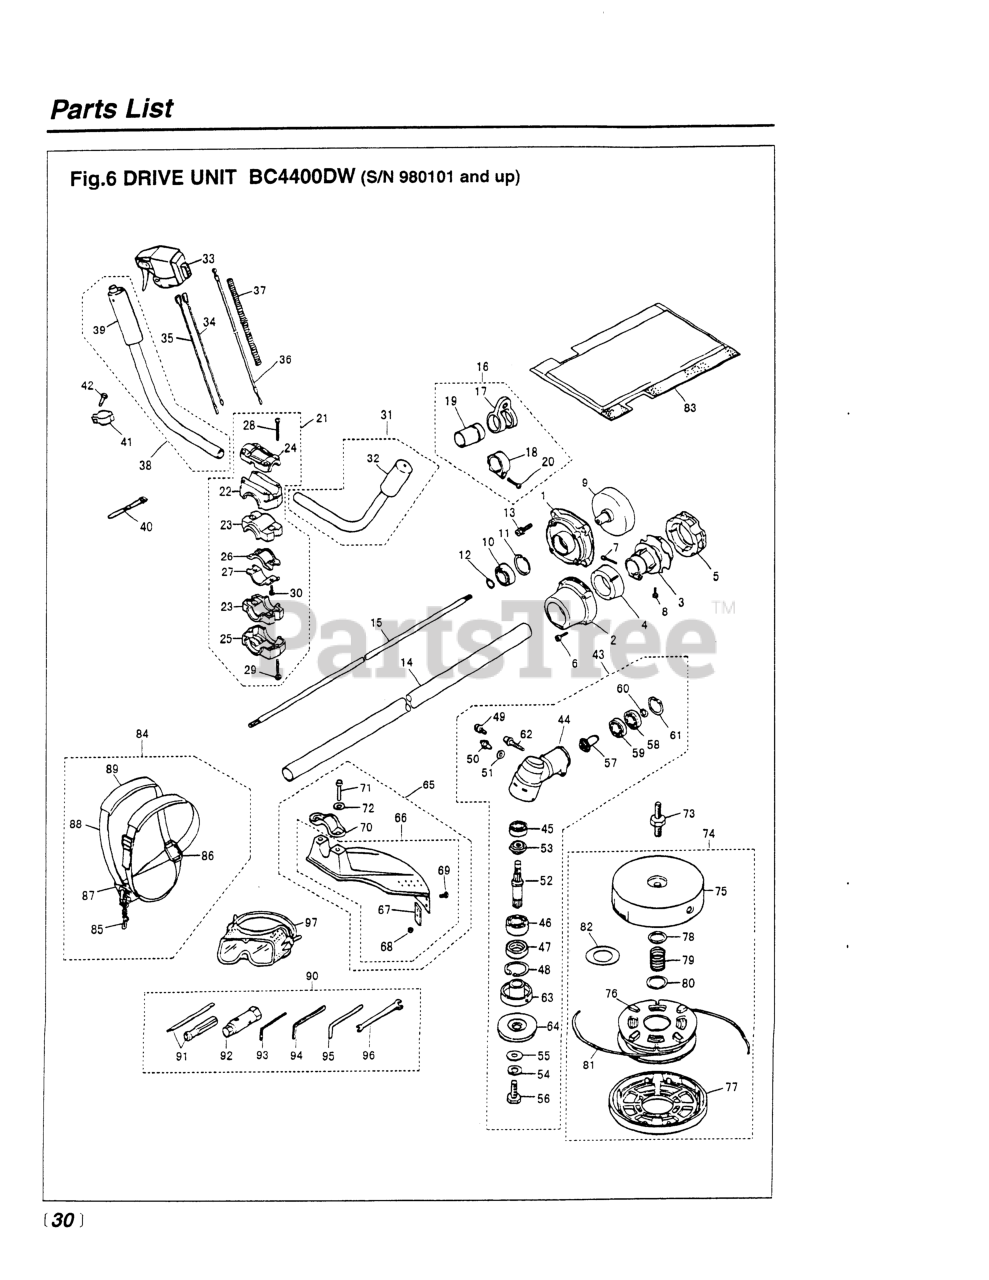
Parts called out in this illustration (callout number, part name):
1	HOUSING
2	CAP
3	JOINT
4	ABSORBER-F
5	ABSORBER-R
6	BOLT, M5 X 30
7	BOLT, M6 x 30
8	BOLT, M5 X 10
10	BEARING
11	RING, SNAP, M35 X 1.5
12	RING, SNAP, M15 X 1.0
13	BOLT, M6 x 20
14	PIPE COMPLETE
15	SHAFT (USE -12212)
16	HANGER ASSEMBLY
17	HANGER
18	CLAMP
20	SCREW, M5 x 25
21	BRACKET ASSY.
22	BRACKET (RPLS -14110)
23	ABSORBER
24	CAP, UPPER (RPLS -14191)
25	CAP, LOWER (RPLS -14120)
26	CLAMP (A)
27	CLAMP (B)
28	BOLT, M5 X 25
29	BOLT, M5 X 35
30	BOLT (USE 3310-31720)
31	HANDLE COMPL, LEFT
33	LEVER ASSEMBLY
34	CORD (A), BLACK
35	CORD (B), RED
37	TUBE
38	HANDLE COMPL, RIGHT
39	GRIP
40	BAND
41	CLAMP
42	SCREW, M5 X 16
44	GEARCASE (RPLS -13113)
45	BEARING (RPLS T3403-13510)
47	SEAL, OIL
48	RING, SNAP, M32 x 1.2
49	BOLT, M5 X 10
50	FITTING, GREASE
51	WASHER, M6 X .8
52	SHAFT
53	GEAR, BEVEL
54	WASHER (RPLS 3180-13270)
55	WASHER, M8 x 2.3 (RPLS -20823)
56	BOLT, LH
57	PINION
59	BEARING (RPLS T3403-13510)
60	RING, SNAP
61	RING, SNAP, M26 X 1.2
62	BOLT, M6 x 1.35
63	HOLDER (A)
64	HOLDER (B)
65	GUARD ASSEMBLY
66	GUARD COMP.
67	BLADE
68	NUT
69	SCREW, M5 x 12
70	CLAMP
71	BOLT, M6 x 1.30
72	WASHER, M6 X 15
73	SHAFT (RPLS 3274-99120)
74	6
75	CASE (USE -99112)
77	COVER
78	PLATE, LARGE
80	PLATE, SMALL
81	CORD
82	SPACER
83	PROTECTOR
87	HANGER COMP.
88	BAND (NOT SOLD SEPARATELY)
89	PROTECTOR
90	TOOL SET
91	SCREWDRIVER
93	WRENCH (TOOL)
94	WRENCH (TOOL)
95	BAR
96	SPANNER, 8 X 10 (RPLS 2540- )
